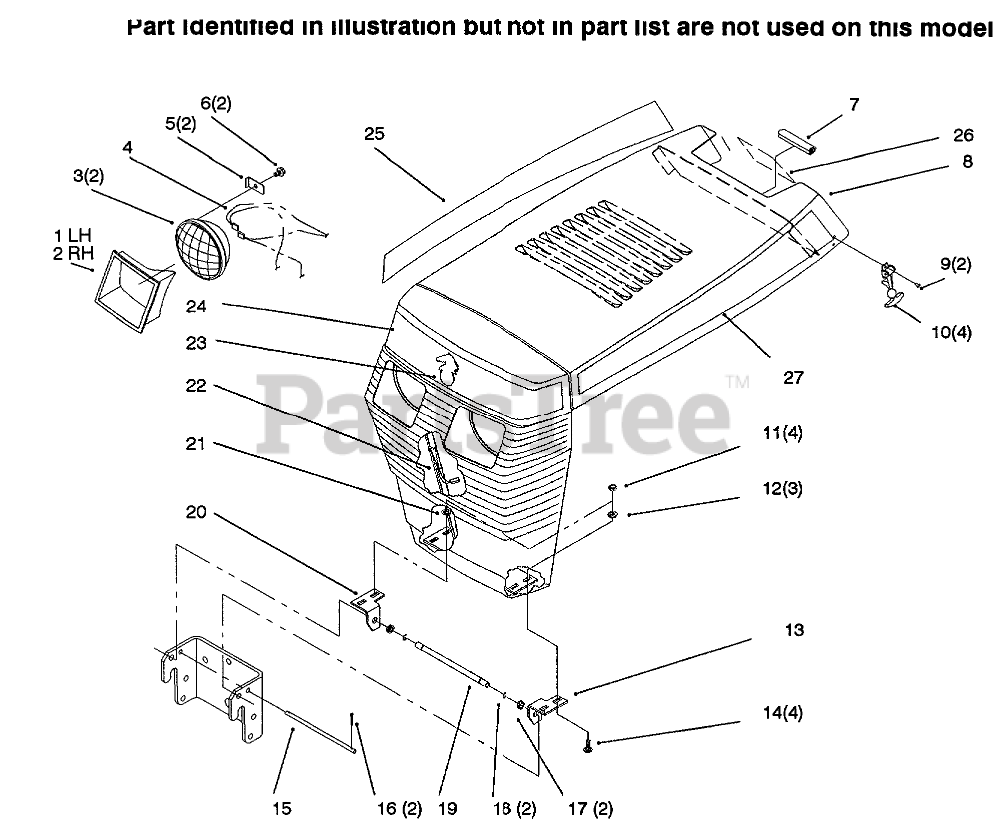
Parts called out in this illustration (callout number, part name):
1	BEZEL-HEADLIGHT, LH
2	BEZEL-HEADLIGHT, RH
3	HEADLAMP
4	HARNESS-HEADLIGHT
5	LOCK-HEADLIGHT
6	SCREW-HWH
7	EDGING-CONSOLE
8	Hood
9	RIVET-POP
10	HANDLE ASM
11	NUT-LOCK, NI
12	WASHER-FLAT
13	BRACKET-GRILL, LH
14	SCREW-CARR
15	ROD-HOOD STOP
16	PIN-COTTER
17	BUSHING-NYLINER
18	RING-RETAINING
19	ROD-GRILL PIVOT
20	BRACKET-GRILL, R H
21	WASHER-LOCK, INTERNAL
22	TIE-CABLE
23	LOGO (GOLD)
24	DECAL-FRONT HOOD, TOP
25	DECAL - RH HOOD TOP
26	DECAL - DANGER
27	DECAL - LH HOOD TOP
